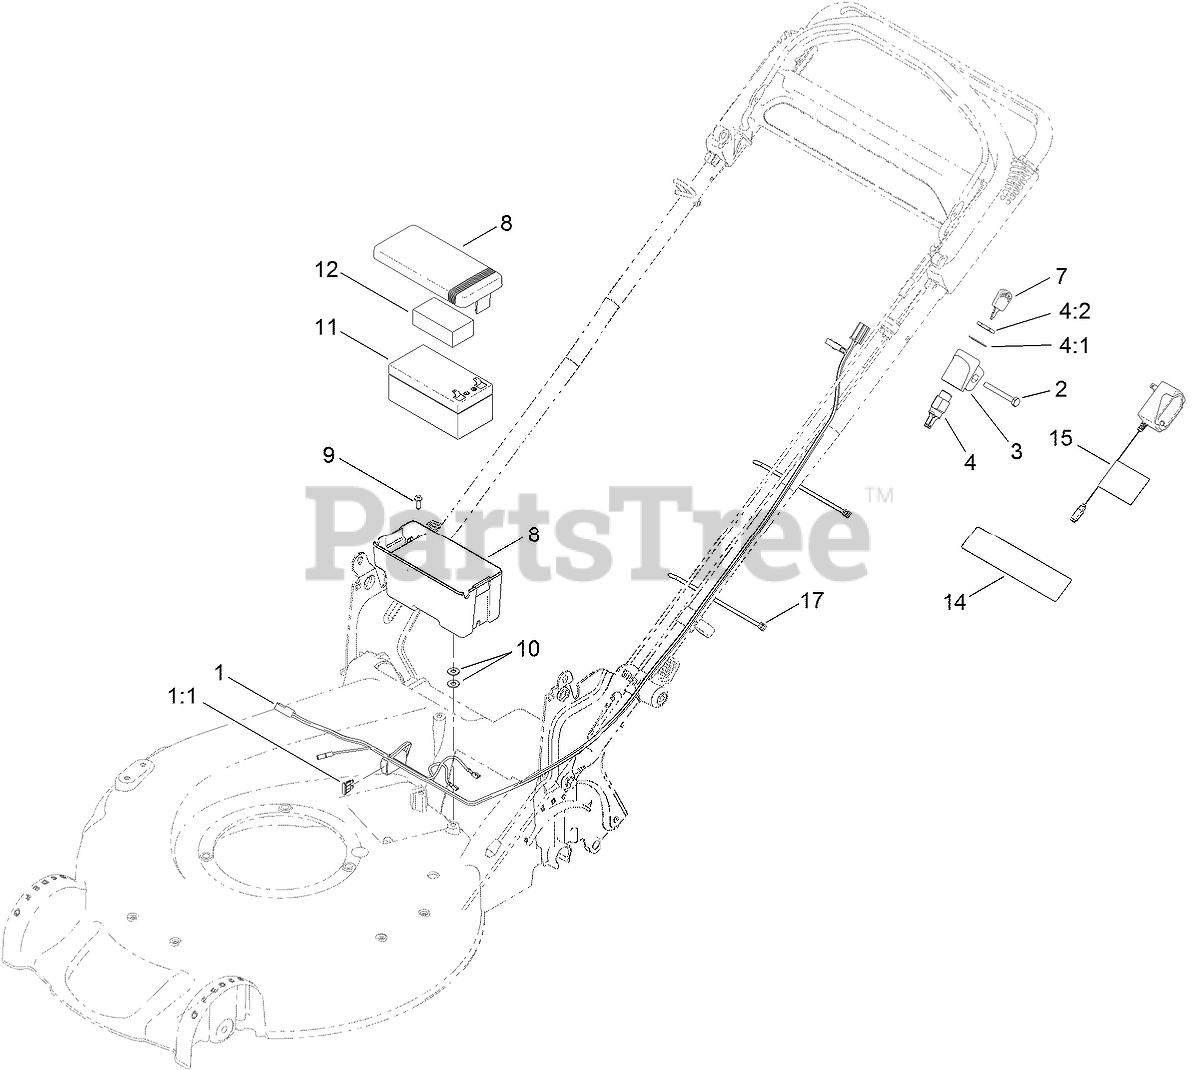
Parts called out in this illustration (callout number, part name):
1	HARNESS-WIRE
1:1	FUSE-40 AMP
2	SCREW-HH
3	MOUNT-SWITCH
4	STARTER SWITCH ASM
4:1	WASHER-TOOTH, INTERNAL
4:2	NUT-HH
8	BATTERY BOX ASM
10	WASHER-FLAT
11	BATTERY-WET
12	FOAM-BATTERY, TOP
14	DECAL-WARNING
15	CHARGER-CE
17	TIE-CABLE
